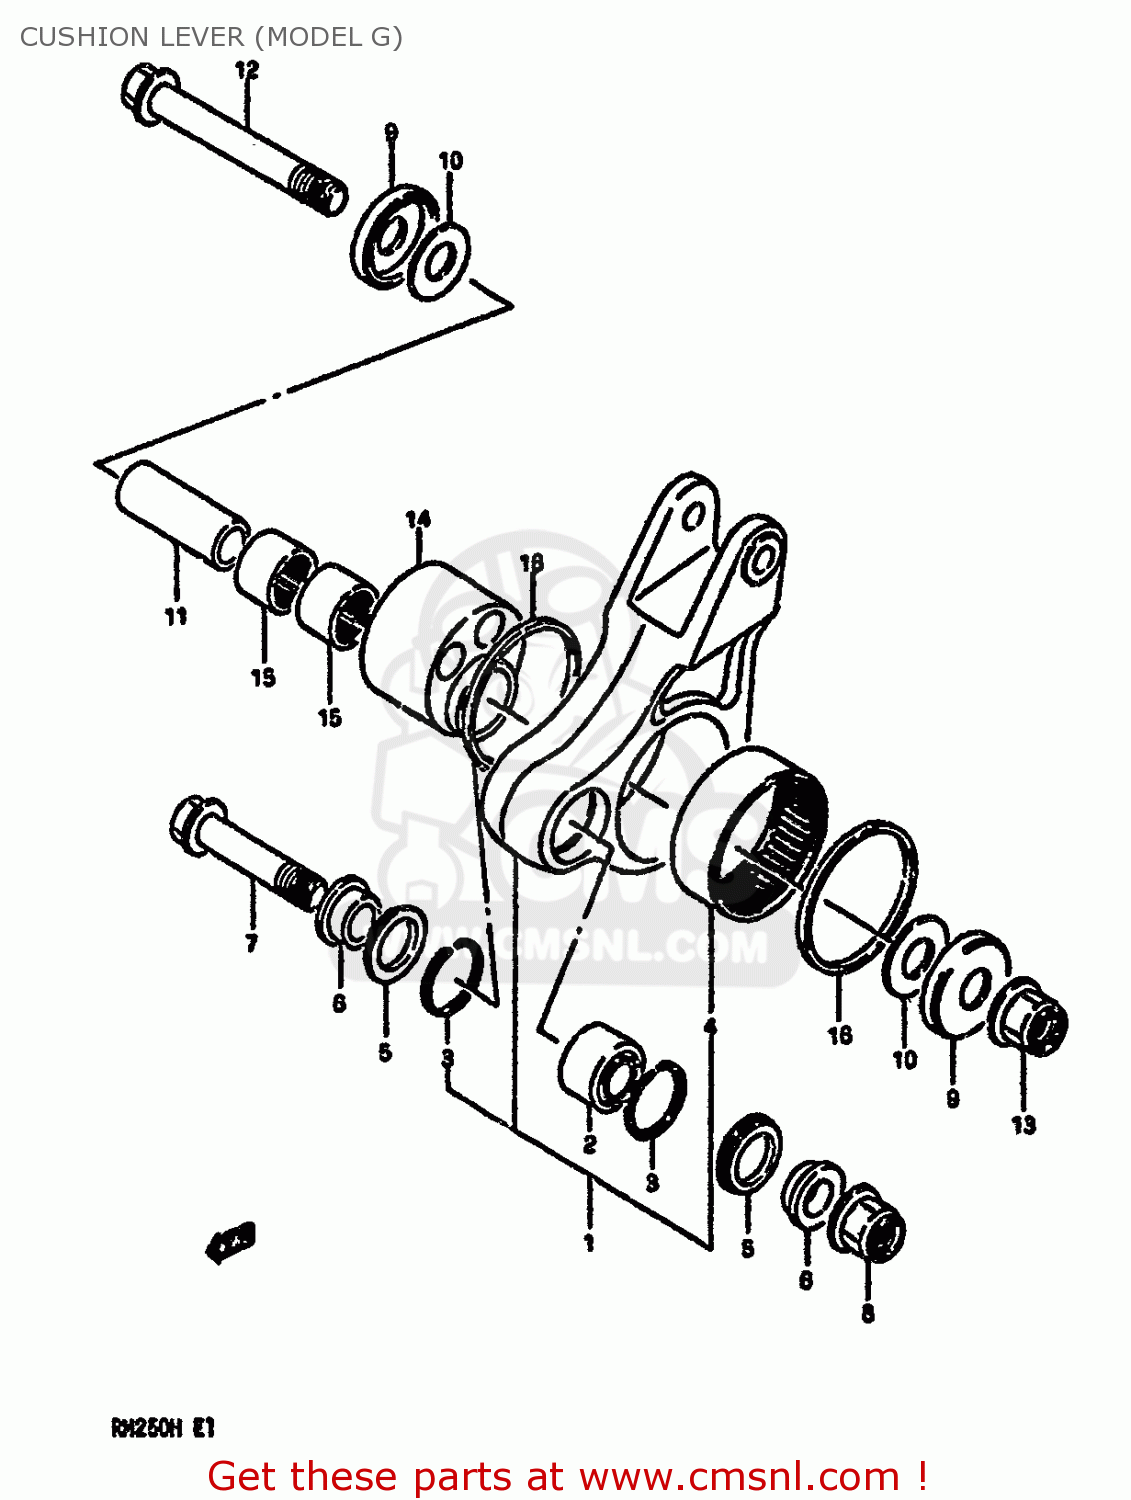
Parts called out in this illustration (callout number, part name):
1	LEVER SET,REAR CUSHION
2	SPHERICAL BEARING (14X3)
3	RING,STOPPER
4	BEARING 55X63X25
5	DUST SEAL,REAR CUSHION,LEFT
6	SPACER,REAR CUSHION LEVER
7	BOLT,RR CUSHION LEVER FR
8	NUT
9	DUST SEAL,RR C
10	WASHER
11	SPACER,RR CUSHION LEVER CTR
12	SHAFT,RR CUSHION LEVER
13	NUT
14	SPACER,RR CUSHION ECCENTRIC
15	BEARING
16	SEAL,REAR CUSHION LEVER
